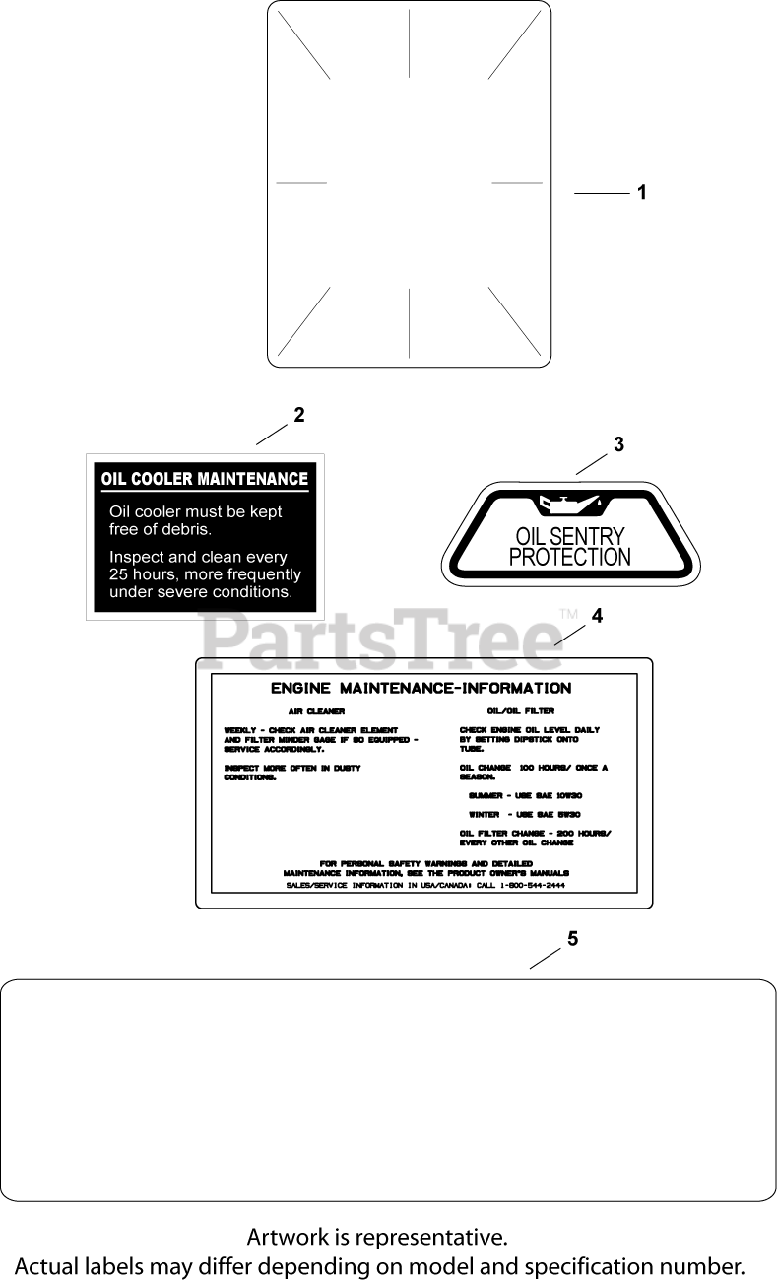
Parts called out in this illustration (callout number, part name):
1	DECAL, CLEAR LAMINATE USE 25 113 70-S
2	DECAL, OIL COOLER - (#DSC)
3	DECAL, OIL SENTRY - (#DSC)
4	DECAL, AIR CLEANER - (#DSC)
5	DECAL, 27 HP
